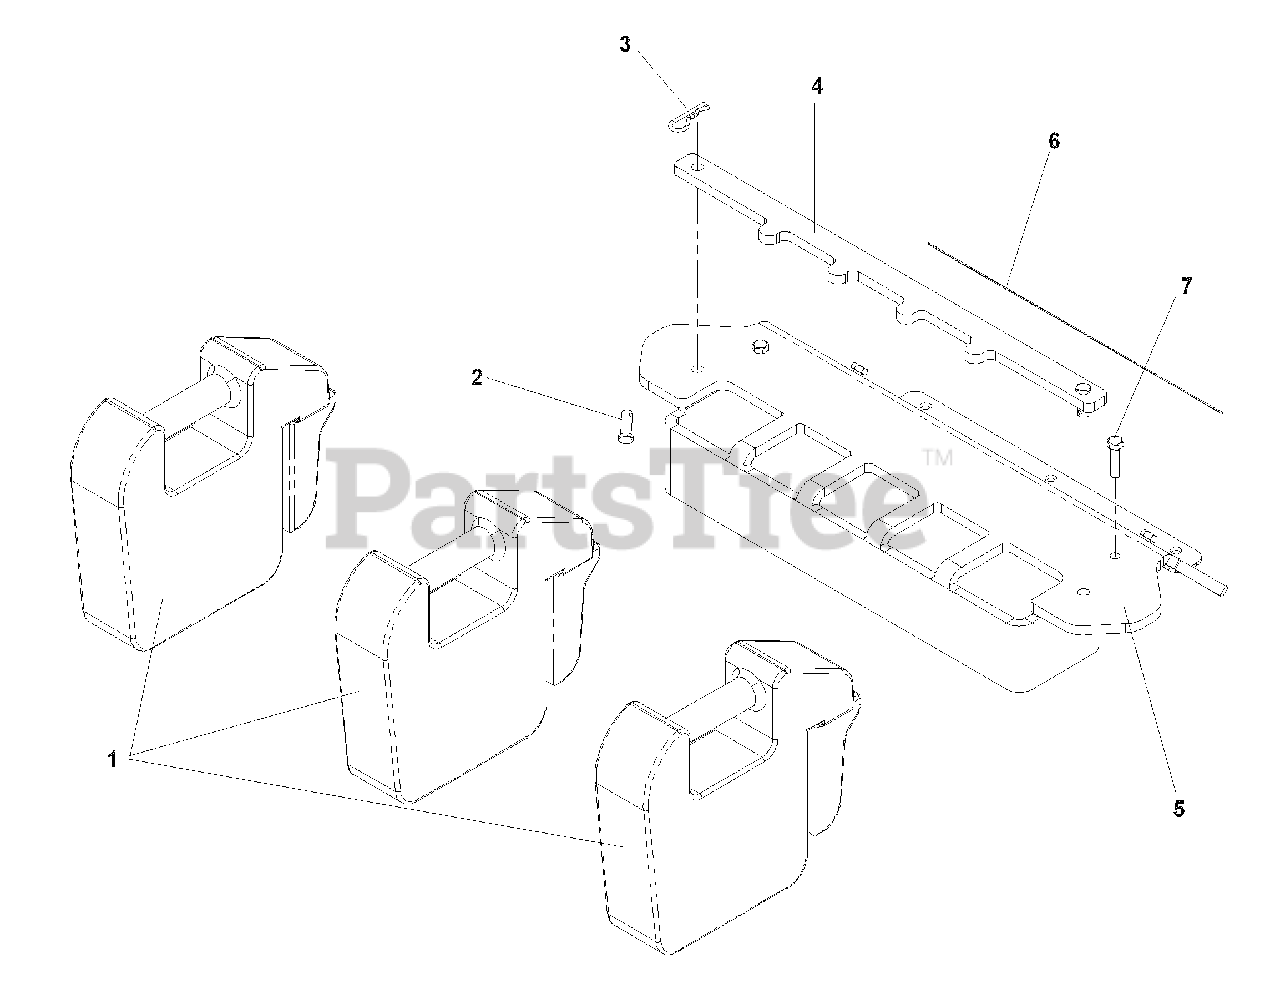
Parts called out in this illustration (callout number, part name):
1	FRONT WEIGHT
2	PINCLEVIS, 3/8x1
3	PINHAIR, 1/8x1 13/16
5	WEIGHT BAR
6	PAD, ABRASIVE
7	HCS, 5/16-18x1 1/4
